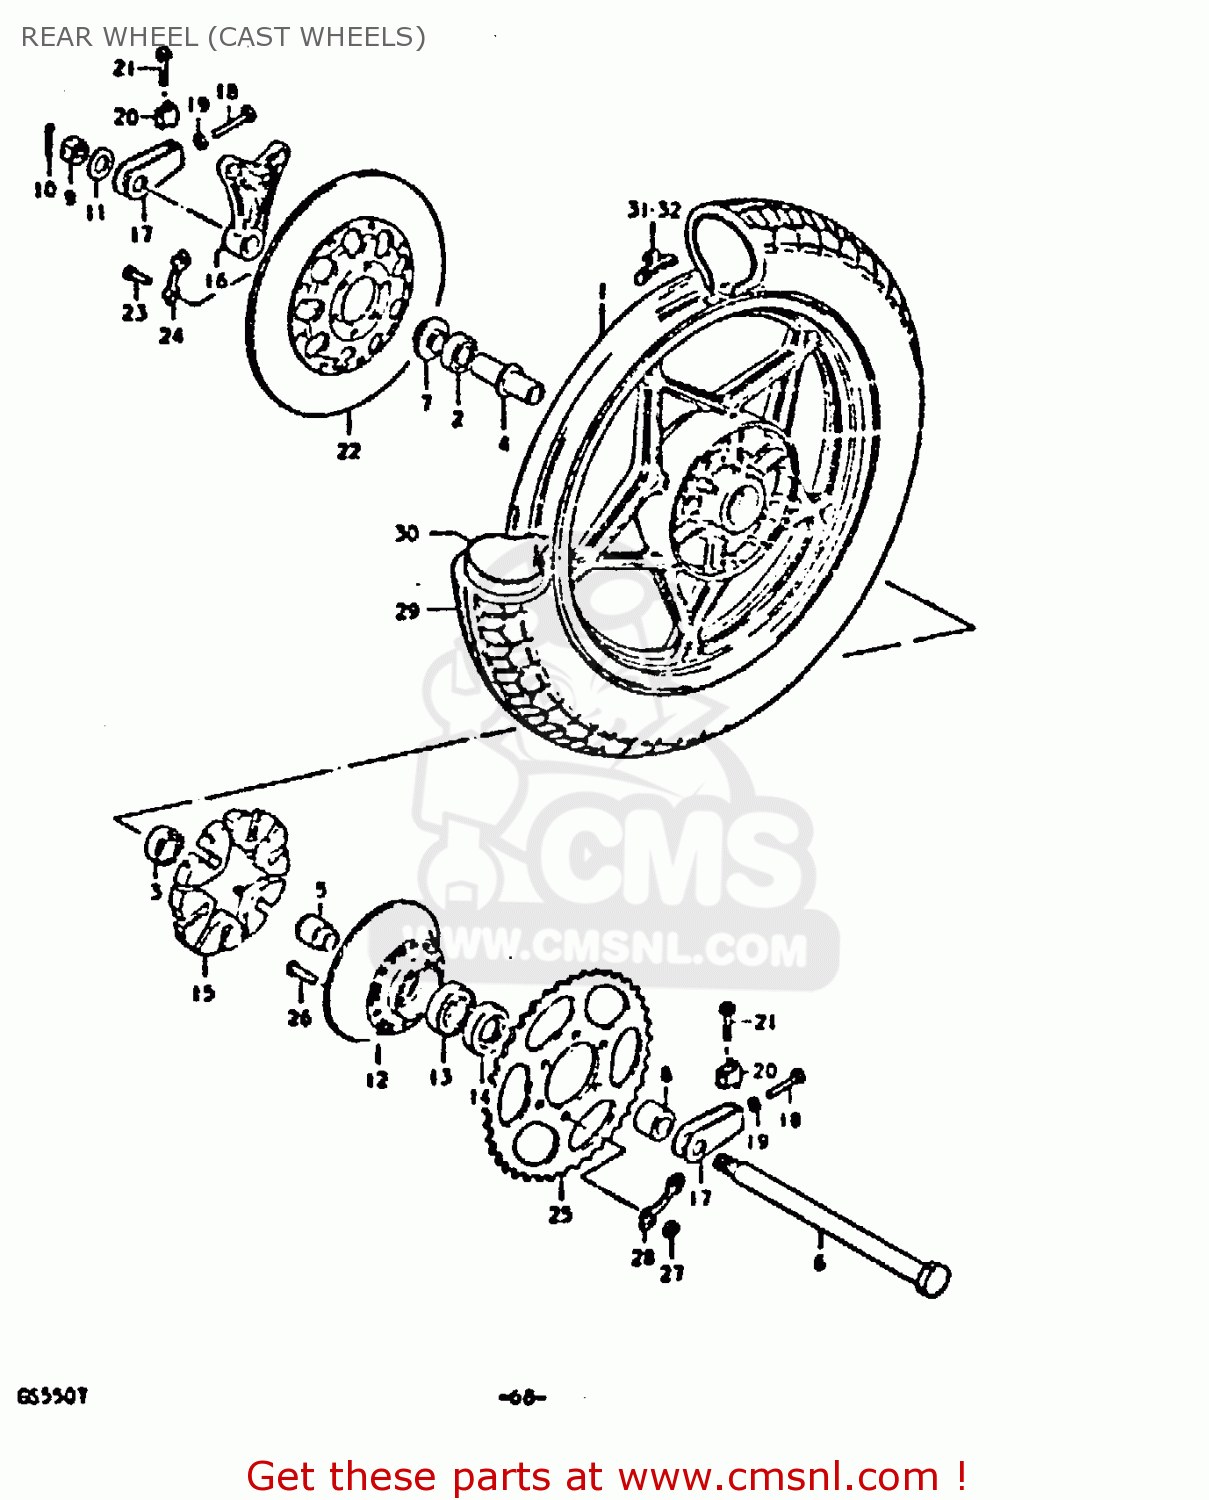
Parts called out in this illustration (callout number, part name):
1	WHEEL, REAR
2	BEARING
3	BEARING
4	SPACER,REAR HUB BEARING
5	RETAINER,REAR SPROCKET D
6	AXLE,REAR
7	SPACER,REAR AXLE
8	SPACER (17X33X21.1)
9	NUT
10	PIN,COTTER
11	WASHER (17X30X3.2)
12	DRUM,REAR SPROCKET MOUNT
13	BEARING
14	SEAL,OIL(33X62X7)
15	ABSORBER,REAR HUB SHOCK
16	BRACKET,RR,CALIPER
17	ADJUSTER,CHAIN
18	BOLT
19	NUT
20	SUPPORTER,CHAIN ADJUST
21	BOLT
22	DISC,BRAKE
23	BOLT(8X30)
24	WASHER
25	SPROCKET,RR
26	BOLT
27	NUT
28	WASHER
29	TIRE
30	TUBE,INNER
31	BALANCER,WHEEL
32	BALANCER,WHEEL
